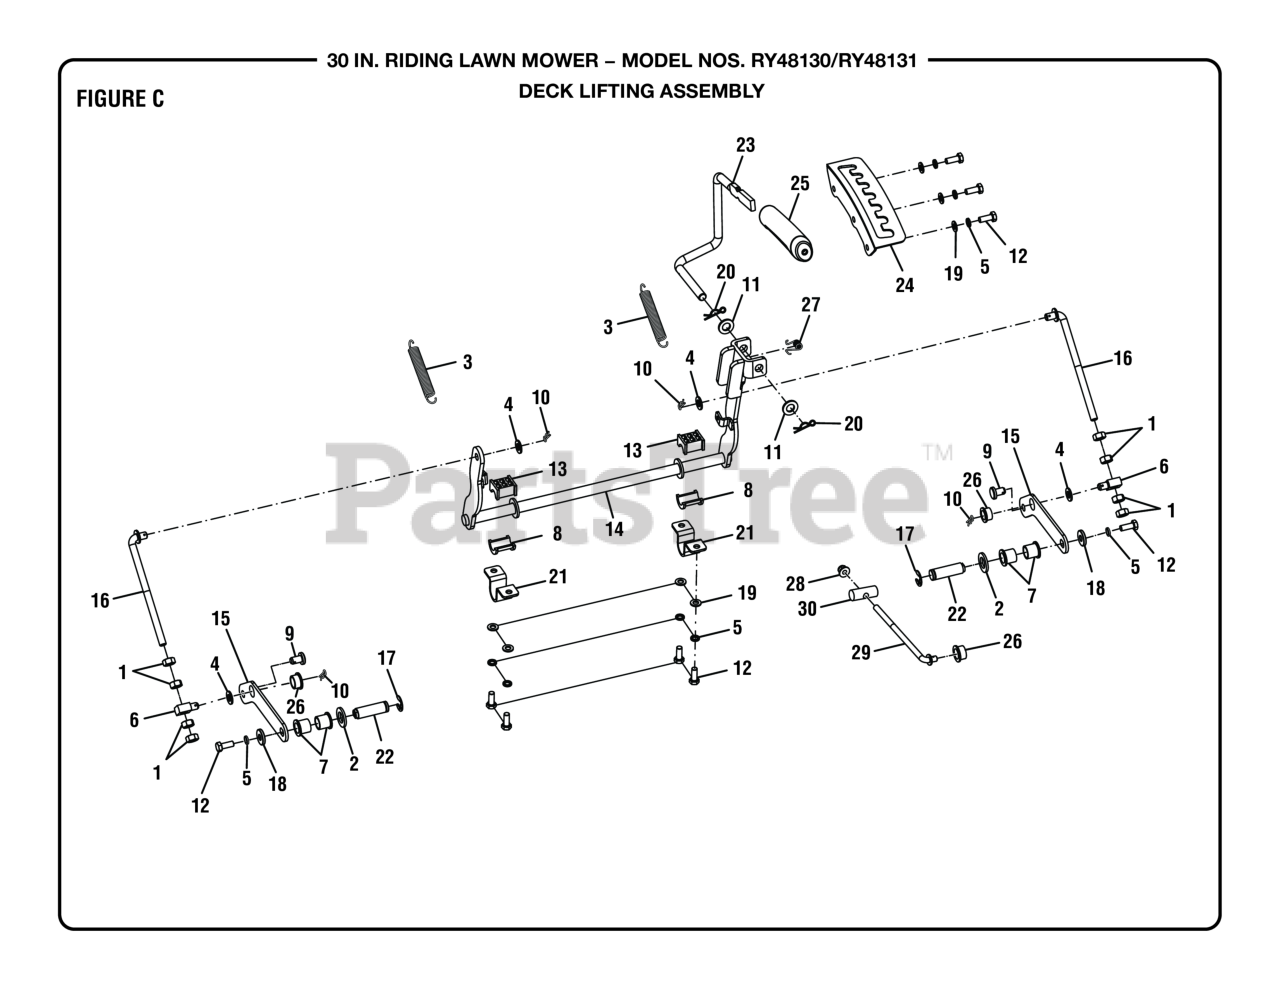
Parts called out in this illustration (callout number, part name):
1	Nut (M10)
2	Washer (OD30 x ID17 x 3t)
4	Washer (OD20 x ID10.5 x 2t)
5	Lock Washer (OD9.8 x ID8.5 x 5t)
6	Hanger Stud Mount
7	Deck Lift Linkage Bushing
8	Bottom Axle Bushing
9	Pin (Rear)
10	Cotter Pin (10 mm)
11	Washer (OD24 x ID13 x 2.5t)
12	Hexagon Bolt (M8 x 20 mm)
13	Top Axle Bushing
14	Rear Deck Lift Assembly
15	Left Deck Linkage
16	J Hook Deck Hanger
17	E-Ring Clip (12 mm)
18	Washer (OD12.5 x ID8.4 x 4t)
19	Washer (OD16 x ID8.4 x 1.6t)
20	Cotter Pin (12 mm)
21	Hanger Bracket Frame Mount
22	Lifting Axle (Rear)
23	Lever Rod
24	Detent Plate
25	Decklift Handle
26	Nylon Bushing
27	Torsion Spring Lever
28	Lock Nut (M10 x 1.5 mm)
29	J Hook (Front)
30	Pivot Axle
